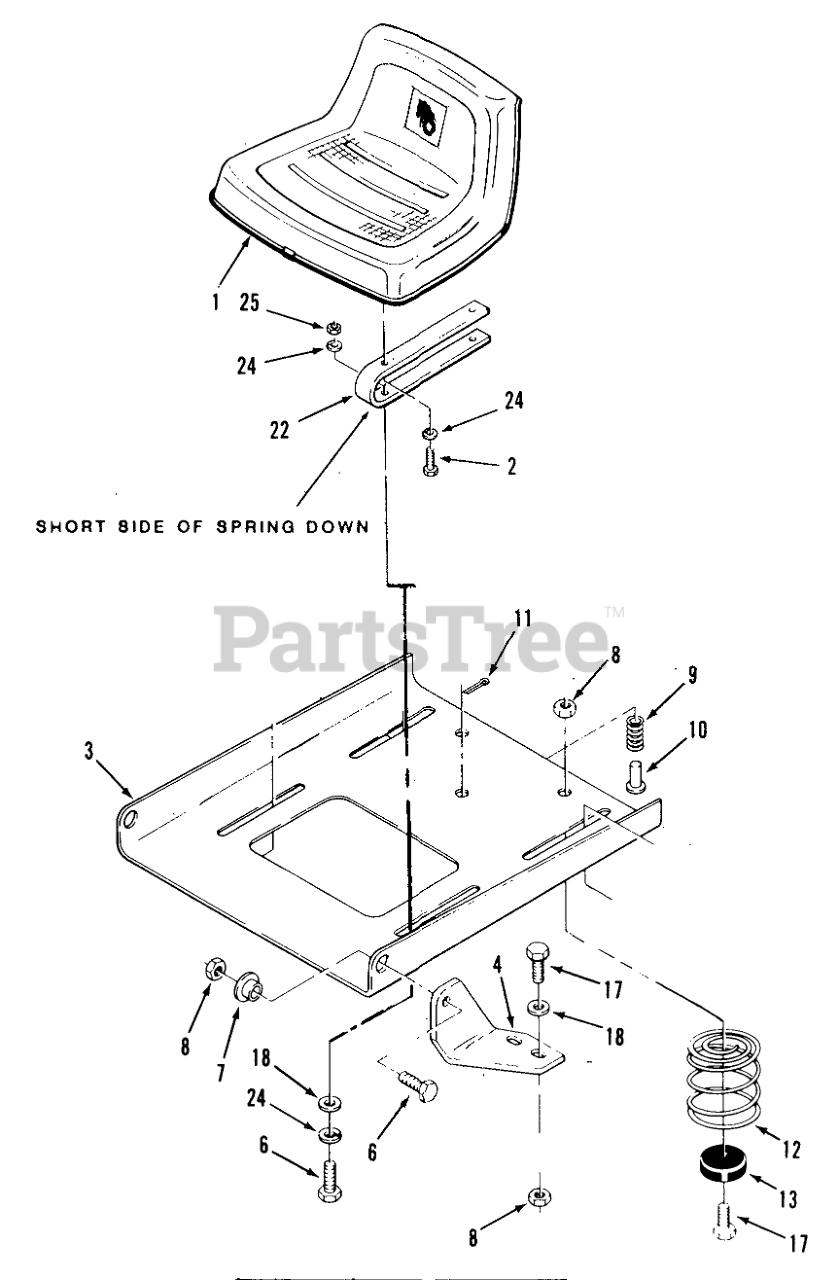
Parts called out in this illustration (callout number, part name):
2	Bolt
3	PLATE-SEAT PIVOT B
4	BRACKET-PIVOT L.H B
6	HHCS
7	BUSHING
8	Nut
9	SPRING-SEAT SWITCH
11	Cotter Pin
12	SPRING
13	BUMPER
17	Bolt
18	WASHER 5/16 SAE
22	Seat Spring
24	Lockwasher
25	Nut
